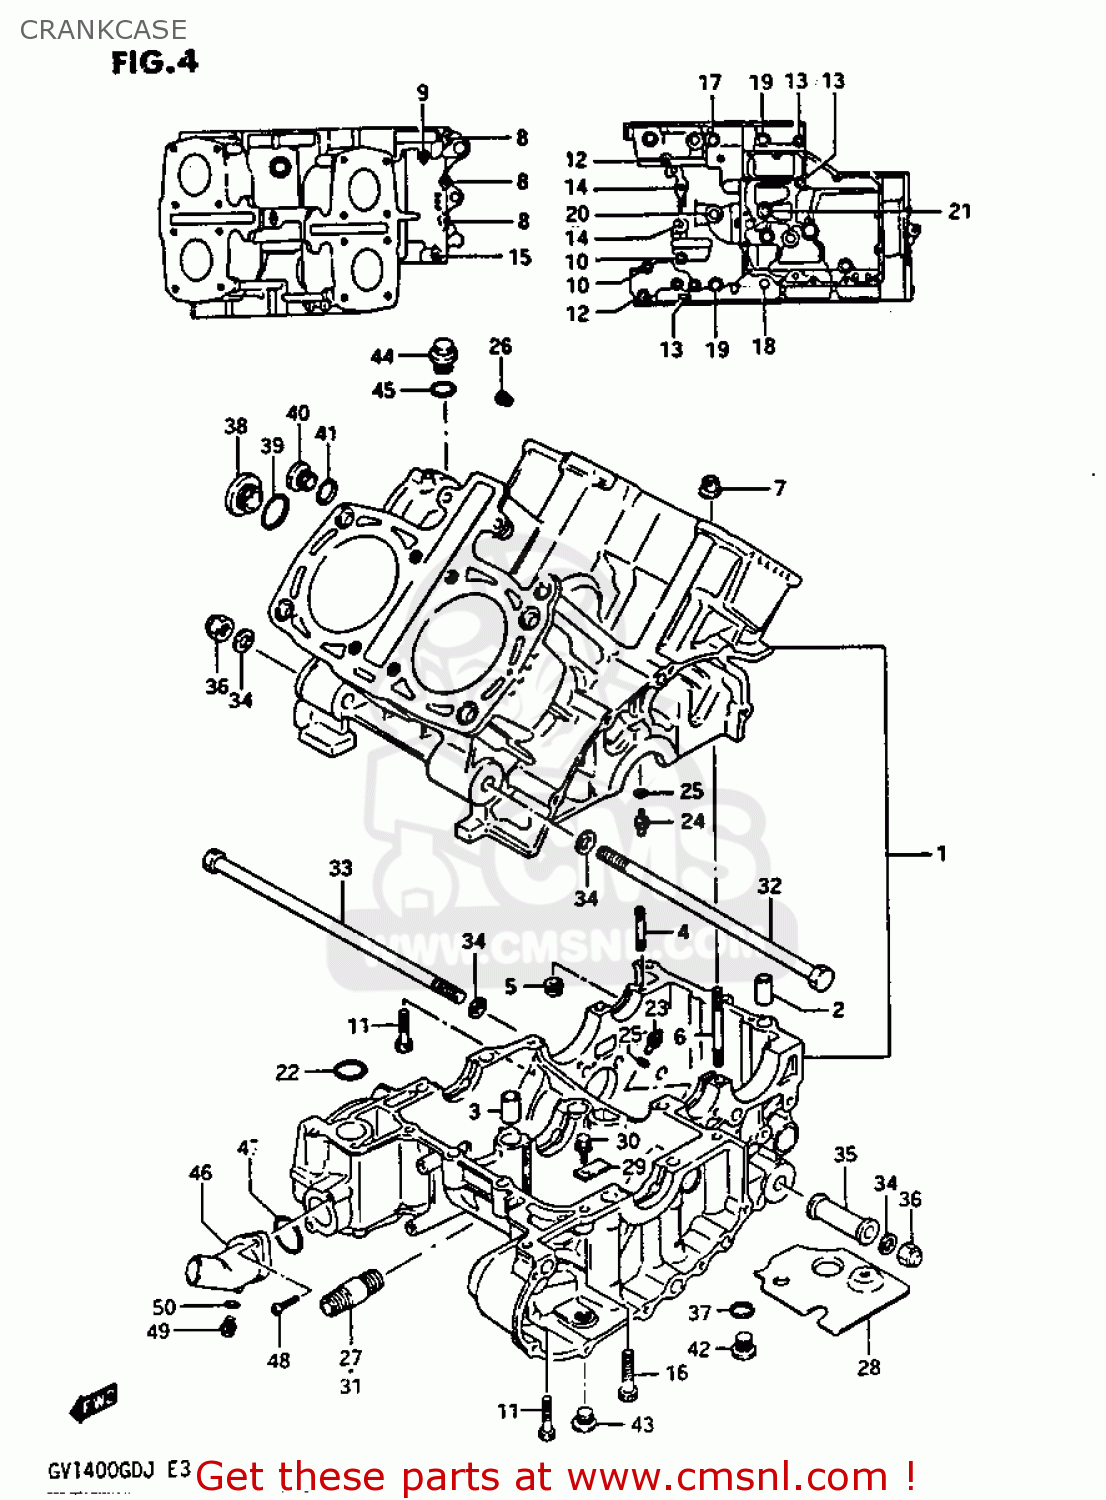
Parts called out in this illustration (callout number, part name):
1	CRANKCASE SET
2	PIN(10.4X13X22)
3	PIN
4	STUD 6X50
5	NUT
6	STUD BOLT
7	NUT 8MM
8	BOLT 6X35
9	BOLT
10	BOLT (6X90)
11	BOLT
12	BOLT(6X100)
13	BOLT(8X125)
14	BOLT
15	BOLT 8X60
16	BOLT 8X35
17	BOLT 10X145
18	BOLT(10X150)
19	BOLT(10X125)
20	BOLT
21	BOLT
22	O-RING (D:3 ID:27)
23	JET,OIL GALLERY
24	JET,OIL GALLERY(16)
25	O RING(D:1.2,ID:4)
26	PLUG OIL GALLER
27	UNION,OIL STAND
28	PLATE,OIL SEPARATOR
29	MAGNET, DUST CATCH
30	BOLT 6X12
31	UNION,OIL STAND
32	BOLT
33	BOLT
34	WASHER 10MM
35	SPACER,ENG MTG(L:55)
36	NUT
37	GASKET(16X22X2) (NAS)
38	PLUG
39	O-RING
40	PLUG
41	O RING(D:3.1,ID:16.8)
42	PLUG
43	PLUG
44	PLUG
45	O RING(D:3.1,ID:16.8)
46	CONNECTOR,WATER INLET
47	O RING(D:2.4,ID:31.7)
48	SCREW
49	BOLT,DRAIN
50	GASKET 8.2X14X1 (NAS)
